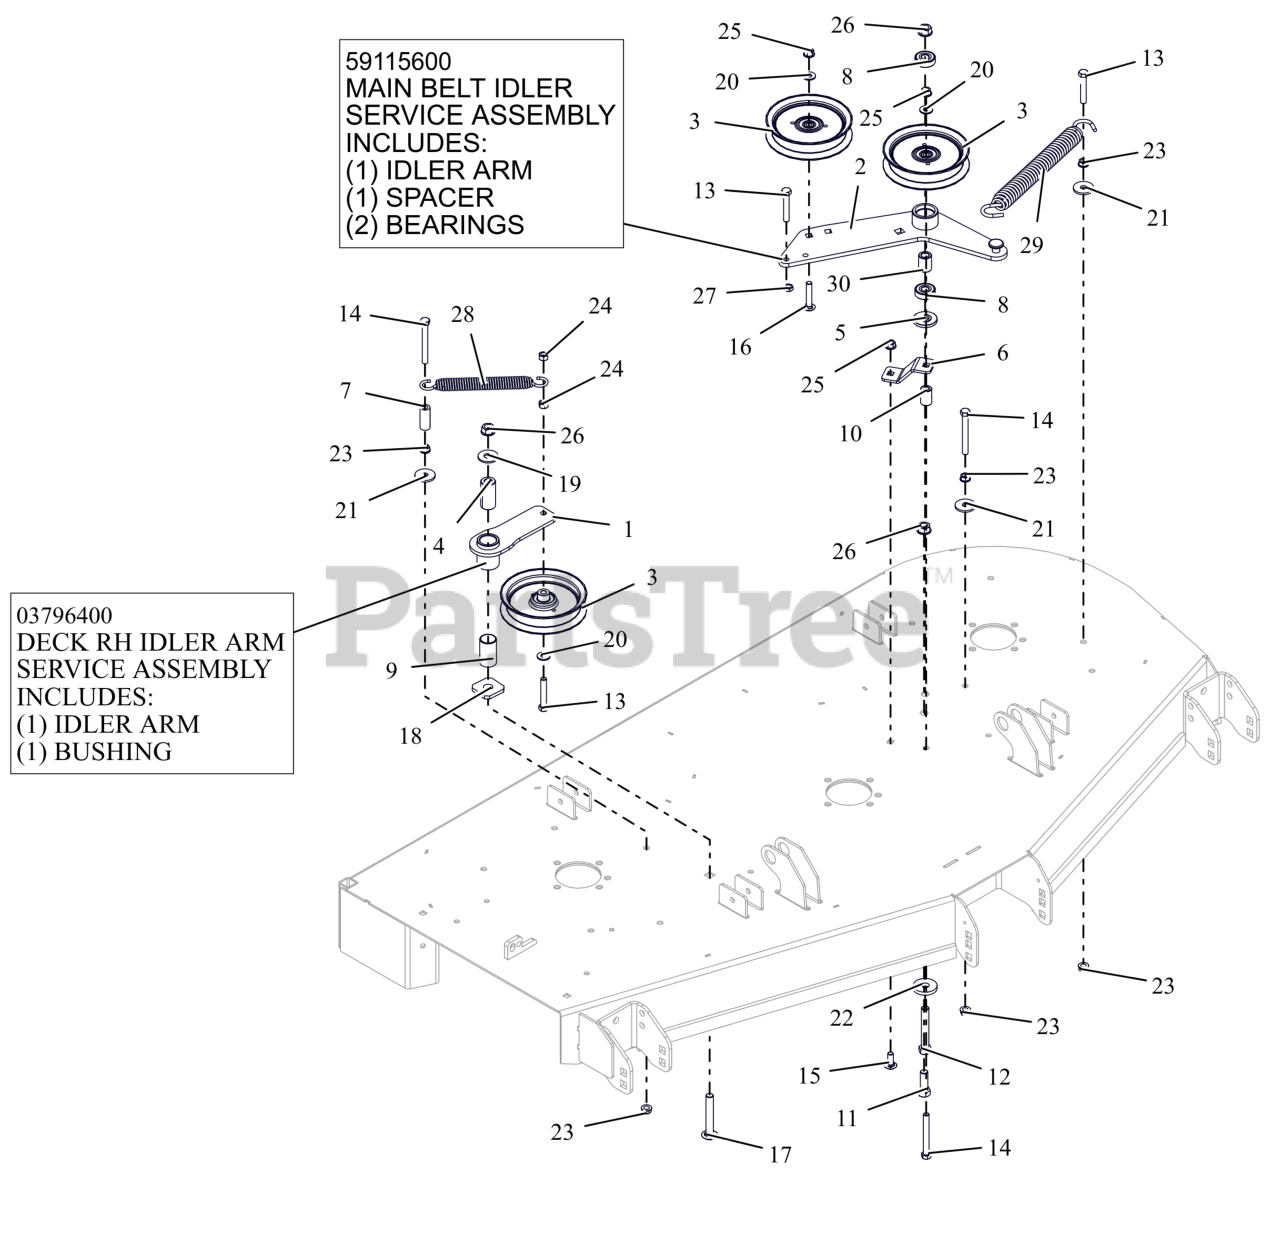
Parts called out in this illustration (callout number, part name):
1	WMT, IDLER ARM - BLACK
1	ASM, IDLER ARM (DECK)
2	WLDMT, DECK PTO IDLR ARM
2	ASSEMBLY, MAIN BELT IDLER
3	IDLER, FLAT 5.00"
4	BSHG, SPCR .502X.997X2.03 PM
5	SPACER, IDLER ARM
6	PTO FIXED IDLER MTG BRKT -RED
7	HOSE, .38 X 1.65
8	BRG-BALL .500X1.38X.437
9	BSHG, 1.00X1.125X1.937
10	BUSHING, SLV .380X.750X1.190
11	BLT,HEX .50-13X1.50 G5 ZCC
12	BLT,HEX .50-13X3.25 G5 ZCC
13	BLT,HEX .38-16X2.25 G5 ZCC
14	BLT, HEX .38-16X3.25 G5 ZCC
15	BLT,RHSSN .38-16X1.00 G5 ZCC
16	BLT,RHSSN.375-16X2.00 G5 ZCC
17	BTL,RHSSN .500-13 X 3.25 G5 ZCC
18	WSHR-FLT .640X1.75X.250
19	WSHR,FLT .563X1.375X.109 ZCC
20	WSHR,FLT .375X.875X.083 ZCC
21	WSHR,FLT .406X1.375X.135 ZCC
22	WSHR-FL-STL 0.557X1.625X0.25 ZCC
23	NUT, SPNLK-FLG .38-16 G5 ZCC
24	NUT-LK-CTR .38-16 ZC120
25	NUT-LK-CTR-FLG .375-16 GF ZCC
26	NUT-LK-CTR-FLG .500-13 GG ZCC
27	NUT-JAM .375-16 G2 ZCC
28	SPRING, EXTENSION
29	SPRING, EXTENSION
30	SPACER .510 X .75 X 1.1485
